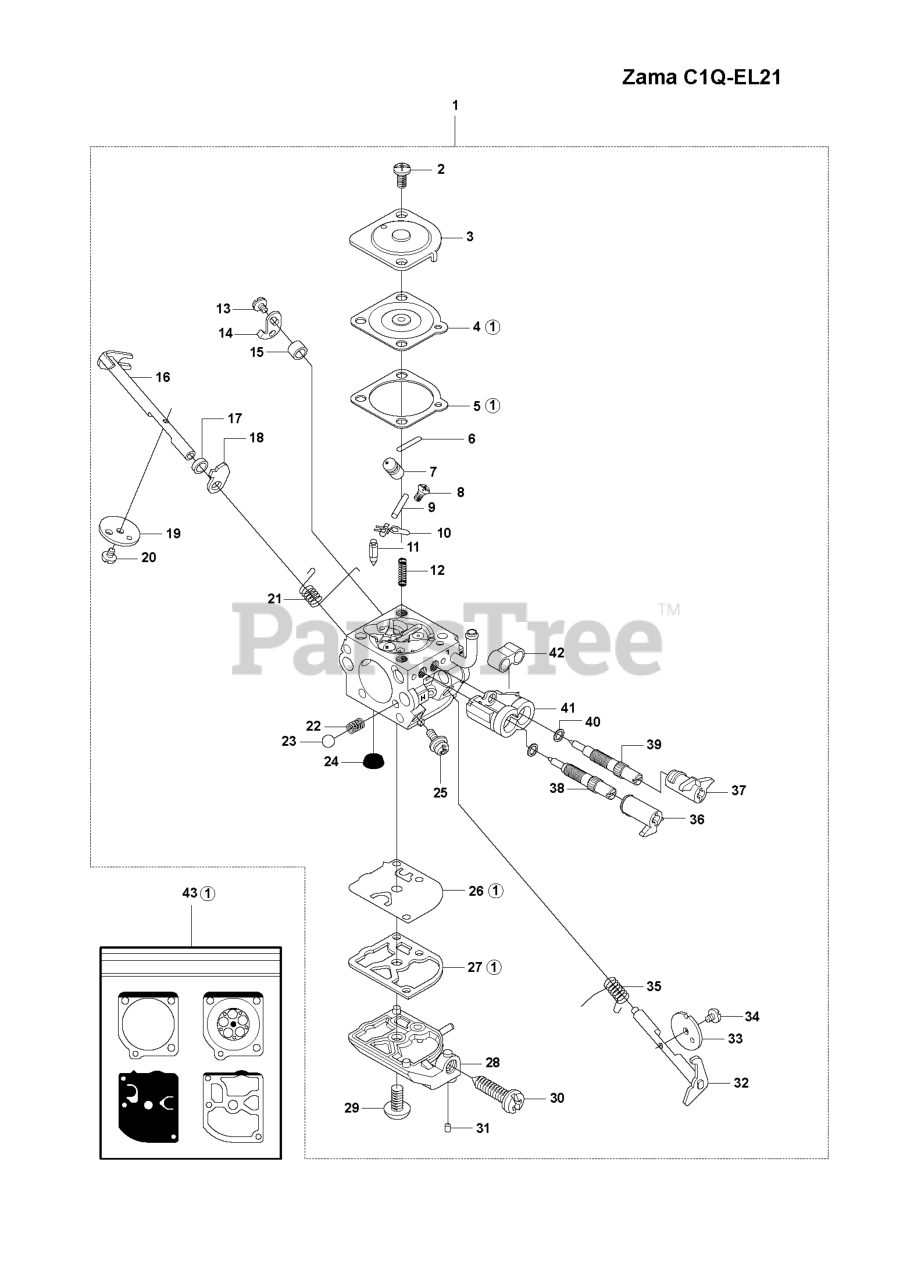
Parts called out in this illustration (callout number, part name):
1	CARBURETOR
2	SCREW
3	COVER
4	METERING DIAPHRAGM
5	GASKET METERING SIDE
6	PLUG
7	SPREADER
8	SCREW
9	PIN FULCRUM
10	LEVER
11	INLET NEEDLE
12	SPRING
13	SCREW
14	LEVER
15	SPACER
16	CHOKE SHAFT
17	BUSHING *
18	LEVER
19	DISC
20	SCREW
21	SPRING
22	SPRING
23	BALL
24	STRAINER
25	SCREW *
26	PUMP DIAPHRAGM
27	GASKET
28	COVER
29	SCREW
30	SCREW
31	PLUG
32	THROTTLE SHAFT
33	THROTTLE FLAP
34	SCREW
35	SPRING
36	LIMITER CAP
37	LIMITER CAP
38	NEEDLE HIGH SPEED
39	NEEDLE LOW SPEED
40	WASHER
41	SLEEVE
42	SLEEVE
43	GASKET SET
